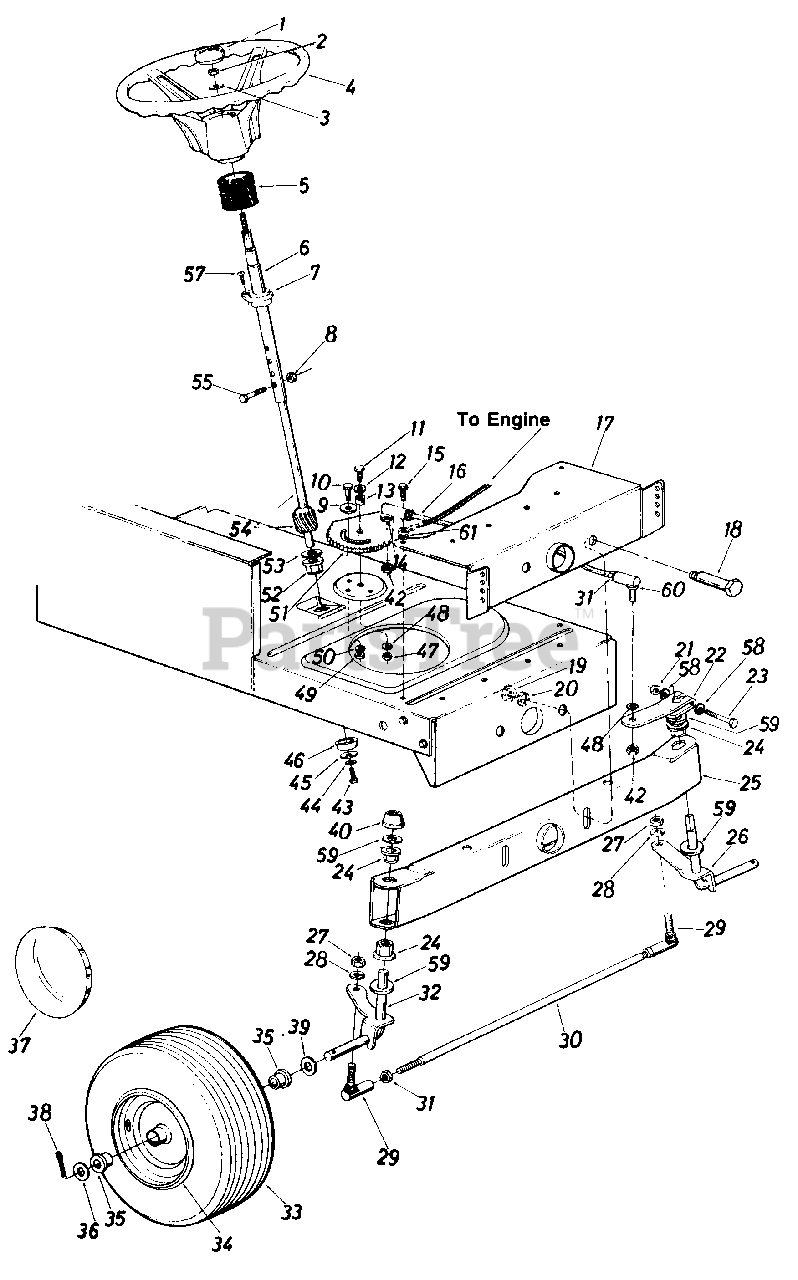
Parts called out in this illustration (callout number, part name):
1	Steering Wheel Cap
2	Hex L-Nut 5/16-24 Thd.
3	Belleville Wash. .345" I.D.
4	Steering Wheel
5	Steering Bellow
6	Steering Column Ass'y.
7	Flange Bearing .890 I.D. x 1.36 O.D.
8	Hex L-Nut 1/4-20 Thd.
9	Fl-Wash. .438" I.D. x 1.37"
10	Shoulder Bolt .437" Dia. x .35 Lg. 5/16-18 Thd.
11	Hex Bolt 3/8-24 x 1.0" Lg. (Grade 5)
12	Bell-Wash. .400" I.D. x 1.13"
13	Spacer .380" I.D. x .625" O.D.
14	L-Wash. 3/8" I.D.
15	Hex Wash. Hd. Self-Tap Scr.
16	Steering Drag Link
17	Front Pivot Brkt.
18	Shoulder Bolt 498" Dia. x 2.04 Lg. 3/8-16 Thd.
19	Hex Nut 3/8-16 Thd.
20	L-Wash. 3/8" I.D.
21	Hex Cent. L-Nut 5/16-24 0 Thd.
22	Steering Arm Front Axle
23	Hex Bolt 5/16-24 x 2.00" Lg. (Grade 5)
24	Hex Flg. Brg. .634 I.D.
26	Front Axle Ass'y.-L.H.
27	Hex Nut 3/8-24 Thd.
28	L-Wash. 3/8" I.D.
29	Ball Joint 3/8-24 Thd.
31	Hex Jam Nut 3/8-24 Thd.
32	Front Axle Ass'y.-R.H.
34	Front Wheel Rim Only
35	Bearing
36	Fl-Wash. .635" I.D. x 1.59" O.D.
37	Front Wheel Hub Cap
38	Cotter Pin 1/8" Dia. x 1.25" Lg.
39	Fl-Wash. .640" I.D. x .24" O.D.
40	Push Cap 5/8" Dia. Rod
42	Hex Jam Nut 3/8-24 Thd.
43	Hex L-Bolt 5/16-18 x .62"
44	L-Wash. 5/16" I.D.
45	FI Wash. .33" I.D. x 1.25" O.D.
46	Spacer (Plastic)
47	Hex Nut 3/8-24 Thd.
48	L-Wash. 318" I.D.
49	Hex Nut 5/16-18 Thd.
50	L-Wash. 5/16" I.D.
51	Steering Gear Segment
52	Hex Flg. Brg. .634 I.D.
53	Fl-Wash. (Hardened)
54	Steering Shaft Lower
55	Hex Bolt 1/4-20 x 1.31" Lg.
57	Oval Hd. Cr.-Sunk Scr. #10 x 5/8" Lg.
58	Wave Wash. .32" I.D. x .62"
59	Fl-Wash. (Hardened)
60	Drag Link Ball Joint 3/8-24 Thd.
61	Ext. L-Wash. 5/16" I.D.
